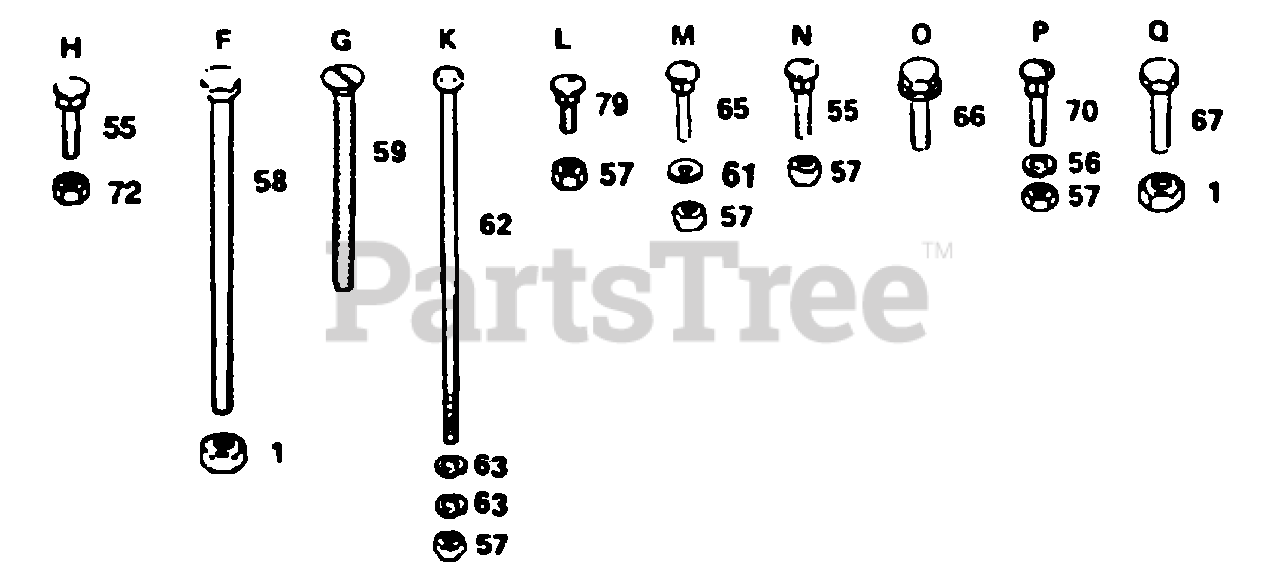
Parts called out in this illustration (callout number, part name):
55	BOLT
56	WASHER
58	BOLT - HEX 3/8 - 16 X 3
59	SCREW YT
61	WASHER M
65	BOLT
66	SCREW
67	BOLT
79	BOLT
